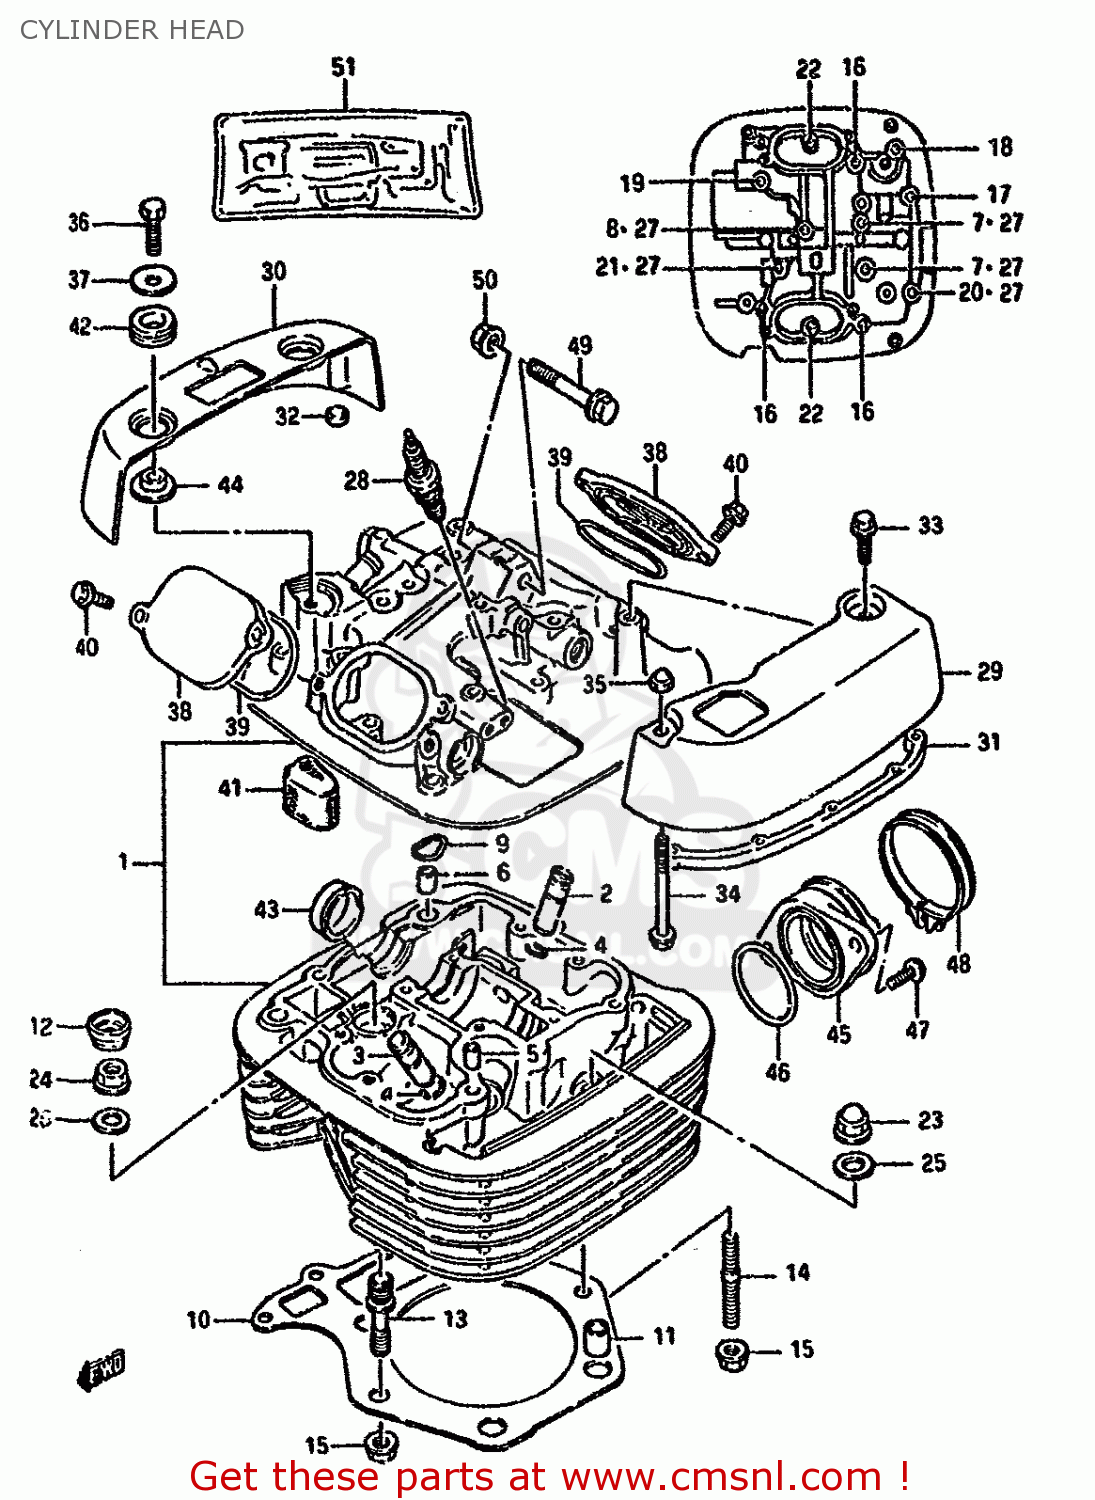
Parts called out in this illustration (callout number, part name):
1	HEAD ASSY,CYLINDER
2	GUIDE,VALVE
3	GUIDE,VALVE
4	RING,SNAP
5	PIN(6.2X8X11)
6	PIN(11X14)
7	BOLT(6X60)
8	BOLT(6X70)
9	O RING,CYL HEAD COVER
10	GASKET,CYLINDER HEAD (NAS)
11	PIN
12	NUT,CYLINDER HEAD SEAL
13	BOLT,STUD
14	BOLT,STUD(8X31)
15	NUT
16	BOLT(6X39)
17	BOLT(6X125)
18	BOLT(6X115)
19	BOLT(6X60)
20	BOLT(6X130)
21	BOLT(6X55)
22	BOLT
23	NUT
24	NUT
25	GASKET(10.5X22X2) (NAS)
26	GASKET(10.2X20X2).3 (NAS)
27	GASKET(5.8X13X1.2) (NAS)
28	SPARK PLUG DP8EA-9
29	CAP,HEAD COVER,L
30	CAP,CYLINDER HEAD COVER,R
31	CUSHION,HEAD COVER CAP,L
32	CUSHION,R CAP
33	BOLT
34	BOLT
35	NUT
36	BOLT
37	WASHER (6.5X24X1.6)
38	CAP,INSPECTION
39	O RING(D:2.4,ID:23)
40	BOLT
41	SEPARATOR,OIL BREATHER COVER
42	CUSHION
43	PLUG(OD:30)
44	BUSH
45	PIPE,INTAKE
46	O RING(D:2.4,ID:45.7)
47	SCREW
48	CLAMP
49	BOLT
50	NUT
51	GASKET SET (NAS)
